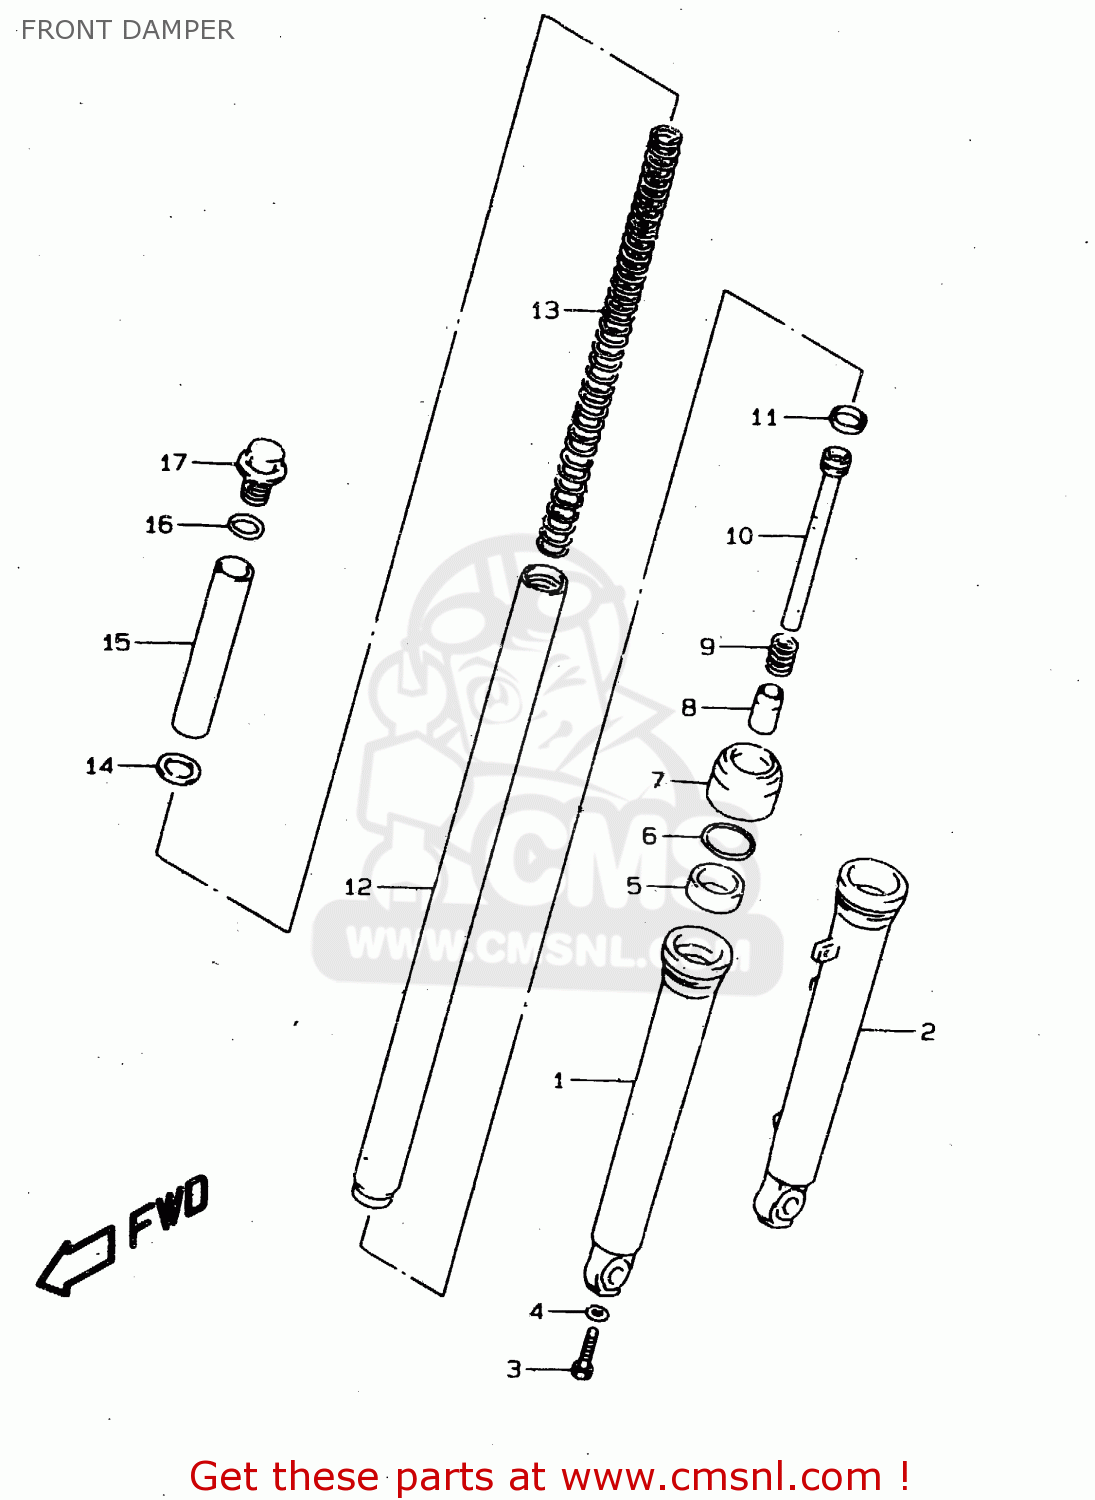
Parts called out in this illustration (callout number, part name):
1	TUBE,OUTER,R
2	TUBE,OUTER,L
3	BOLT(8X27)
4	GASKET (NAS)
5	SEAL,OIL
6	RING,OIL SEAL STOPPER
7	DUST SEAL
8	PIECE,OIL LOCK
9	SPRING,REBOUND
10	CYLINDER,FR FORK
11	RING,PISTON
12	TUBE,INNER
13	SPRING
14	JOINT,SPRING
15	SPACER,SPRING
16	O RING(D:2.4,ID:17.8)
17	CAP
